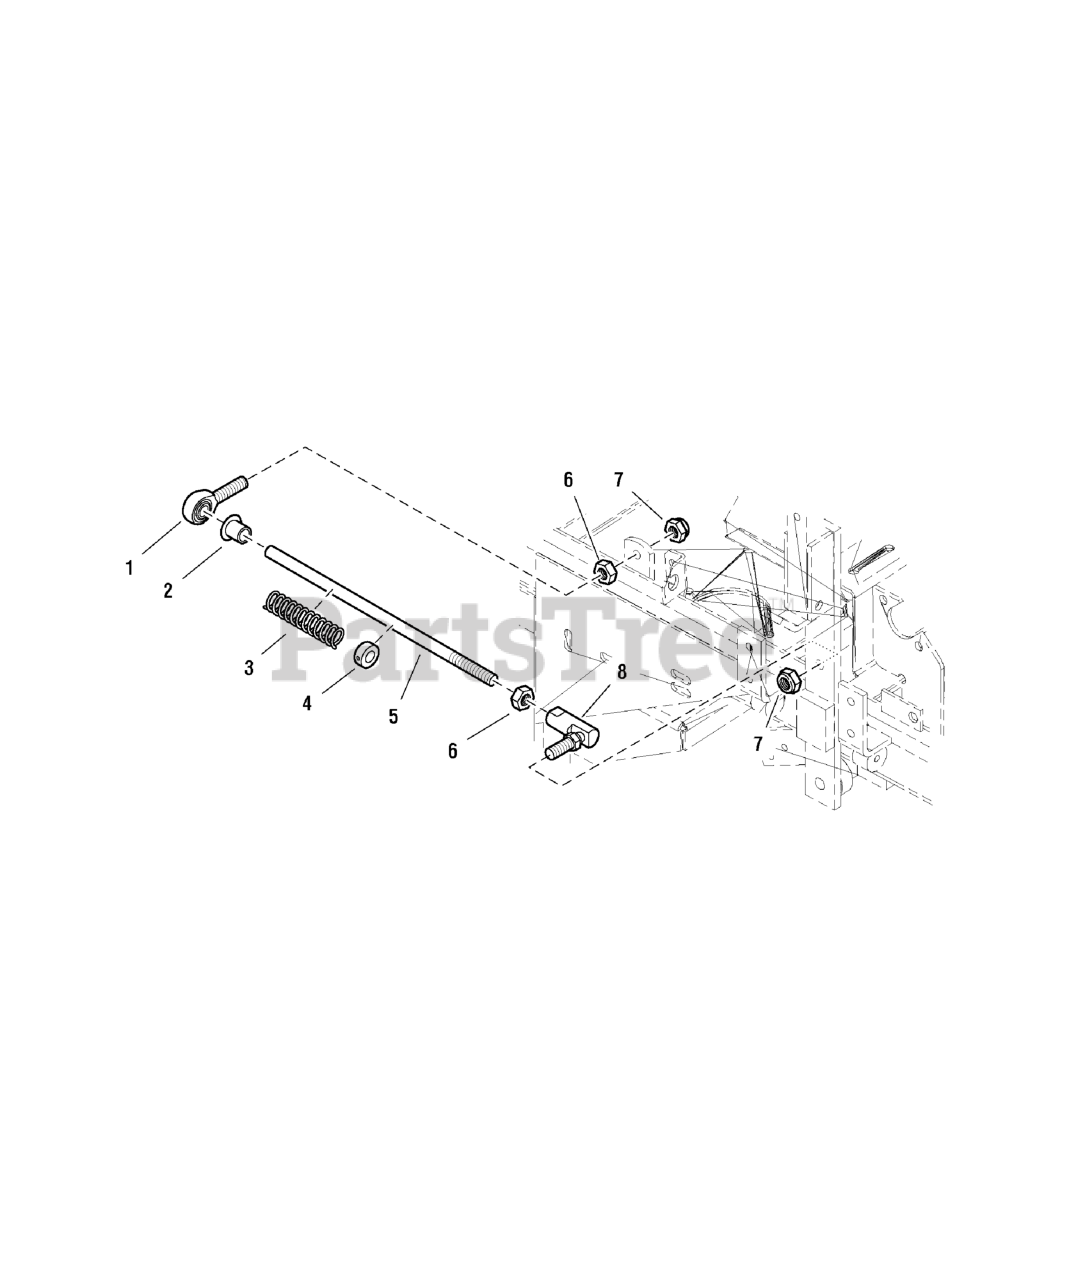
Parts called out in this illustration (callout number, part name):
1	BALL JOINT, 3/8-24 Male
2	BUSHING
3	SPRING, Compression
4	COLLAR, 3/8" Set
5	NEUTRAL CONTROL ROD
6	NUT, 3/8-24 Hex
7	NUT, 3/8-24 Hex Nylon Lock
8	BALL JOINT, 3/8" Female Studded
